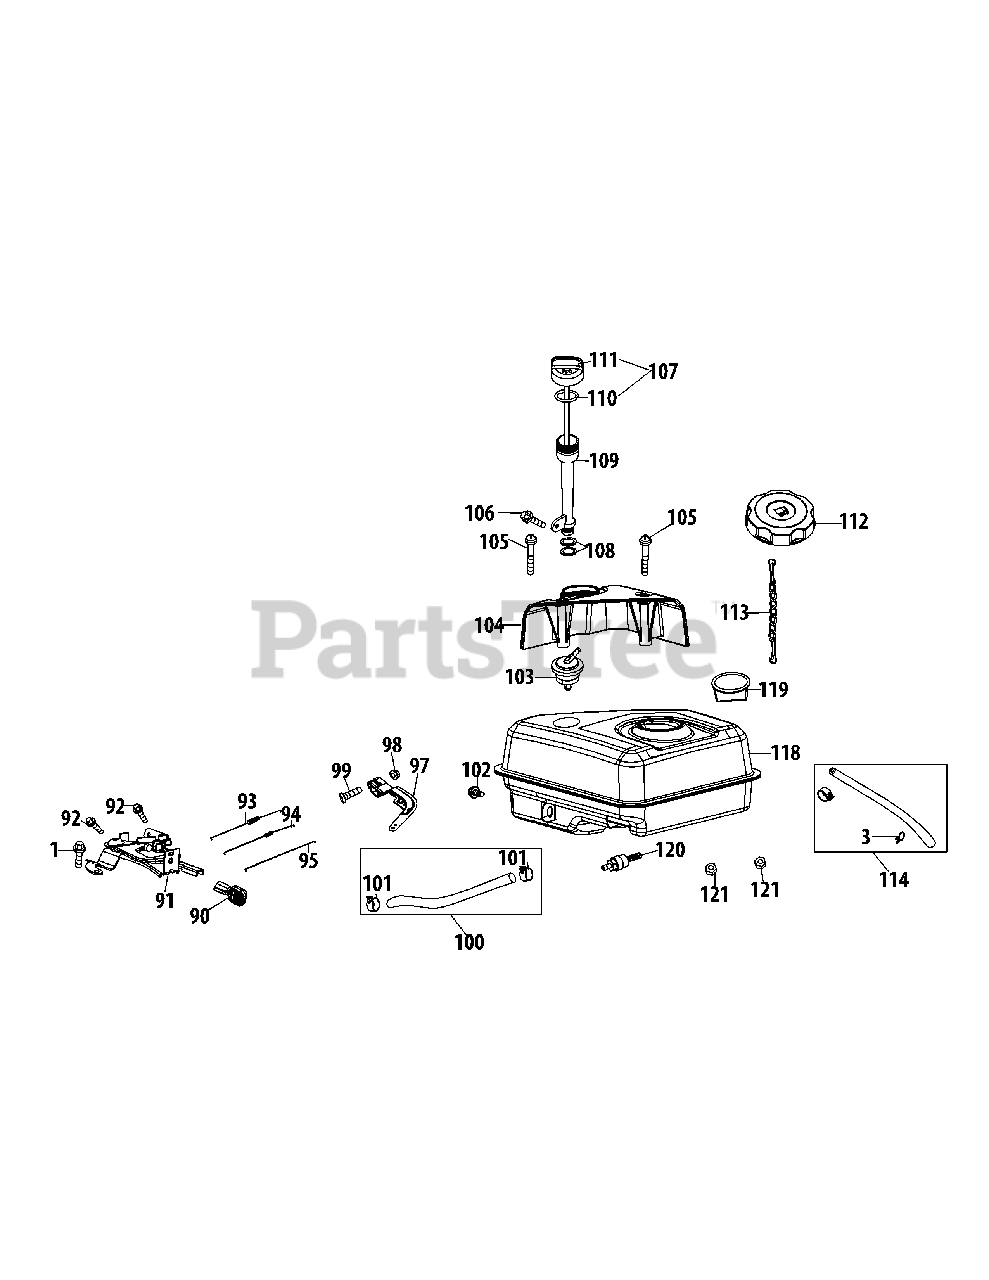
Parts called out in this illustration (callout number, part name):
1	Bolt M6×16
3	Breather Hose Clamp
90	Throttle Control Knob
91	Primer Bracket
92	Bolt M6×12
93	Governor Spring
94	Throttle Linkage Spring
95	Throttle Linkage
97	Governor Arm
98	Nut M6
99	Governor Arm Bolt
100	Fuel Line Kit
101	Fuel Hose Clamp
102	Bolt M6×12
103	Rollover Valve
104	Dipstick Decoration Cover
106	Bolt M6×12
107	Dipstick Assembly
108	O-Ring
109	Oil Fill Tube Assembly
110	O-Ring
111	Dipstick Guage
112	Cap Comp,Fuel
113	Tether
114	Primer Hose
118	Fuel Tank Assembly
119	Fuel Level Indicator
120	Fuel Tank Nipple
121	Nut, M6
